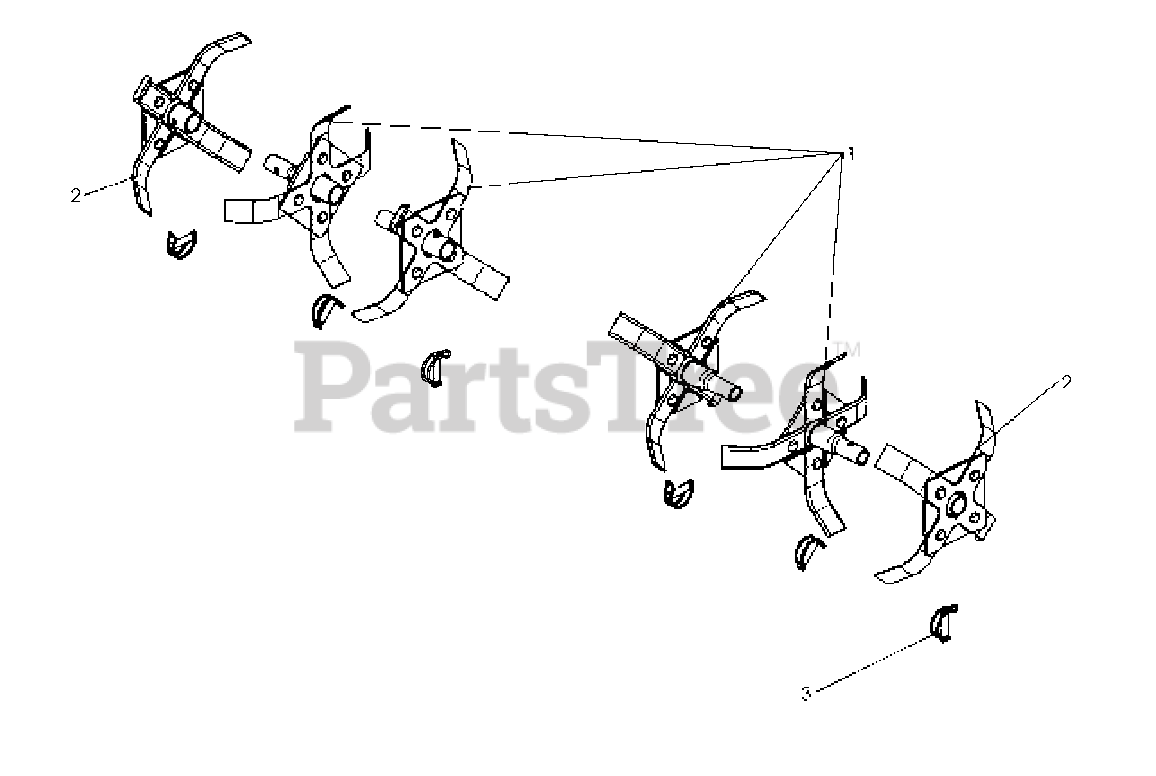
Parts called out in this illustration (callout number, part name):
1	BLADE
2	BLADE
3	PIN
